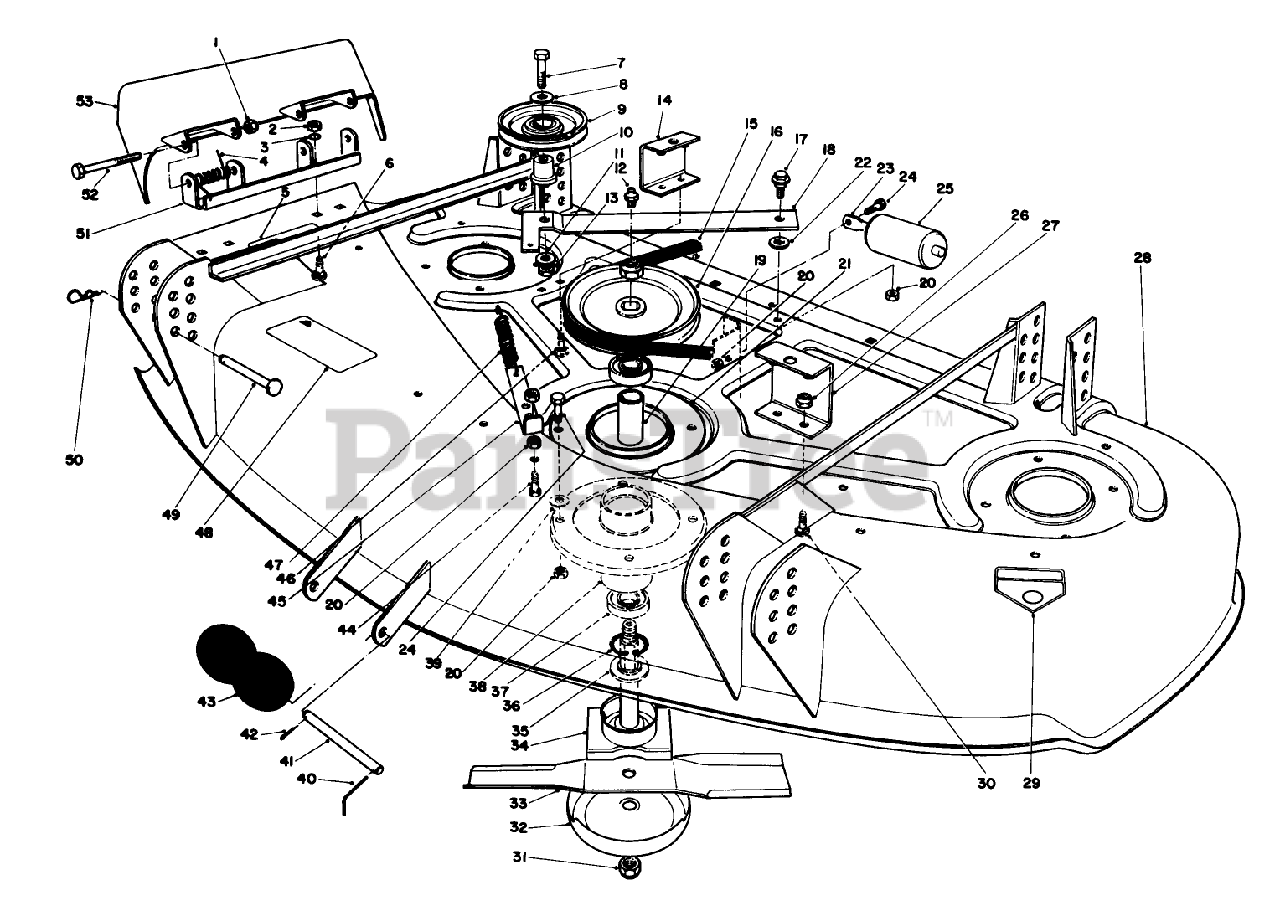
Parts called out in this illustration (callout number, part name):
1	NUT-HEX
2	NUT-HEX
3	SCREW-HH
4	SPRING
7	SCREW-HH
8	WASHER-FLAT
9	PULLEY-IDLER
10	BUSHING-PULLEY
11	WASHER-FLAT
12	FITTING-GREASE
13	NUT-LOCK, CONE
15	V-BELT-DECK
17	SCREW-SHOULDER
20	NUT-LOCK, CONE
22	WASHER
23	ROD-ROLLER
24	SCREW-HH
25	ROLLER-DECK
26	NUT-LOCK, NI
29	DECAL-DANGER
30	SCREW-CARR
31	NUT-LOCK NI
32	Cup
35	IDLER SPACER
37	BEARING-BALL
39	WASHER-FLAT
40	PIN-SPECIAL
41	SHAFT-ROLLER
42	PIN-COTTER
43	ROLLER
44	SCREW-HH
46	SCREW-CARR
47	SPRING-EXTENSION, DECK
49	PIN-CLEVIS
50	PIN-HAIR
51	PIVOT BRKT WA
52	SCREW-HH
